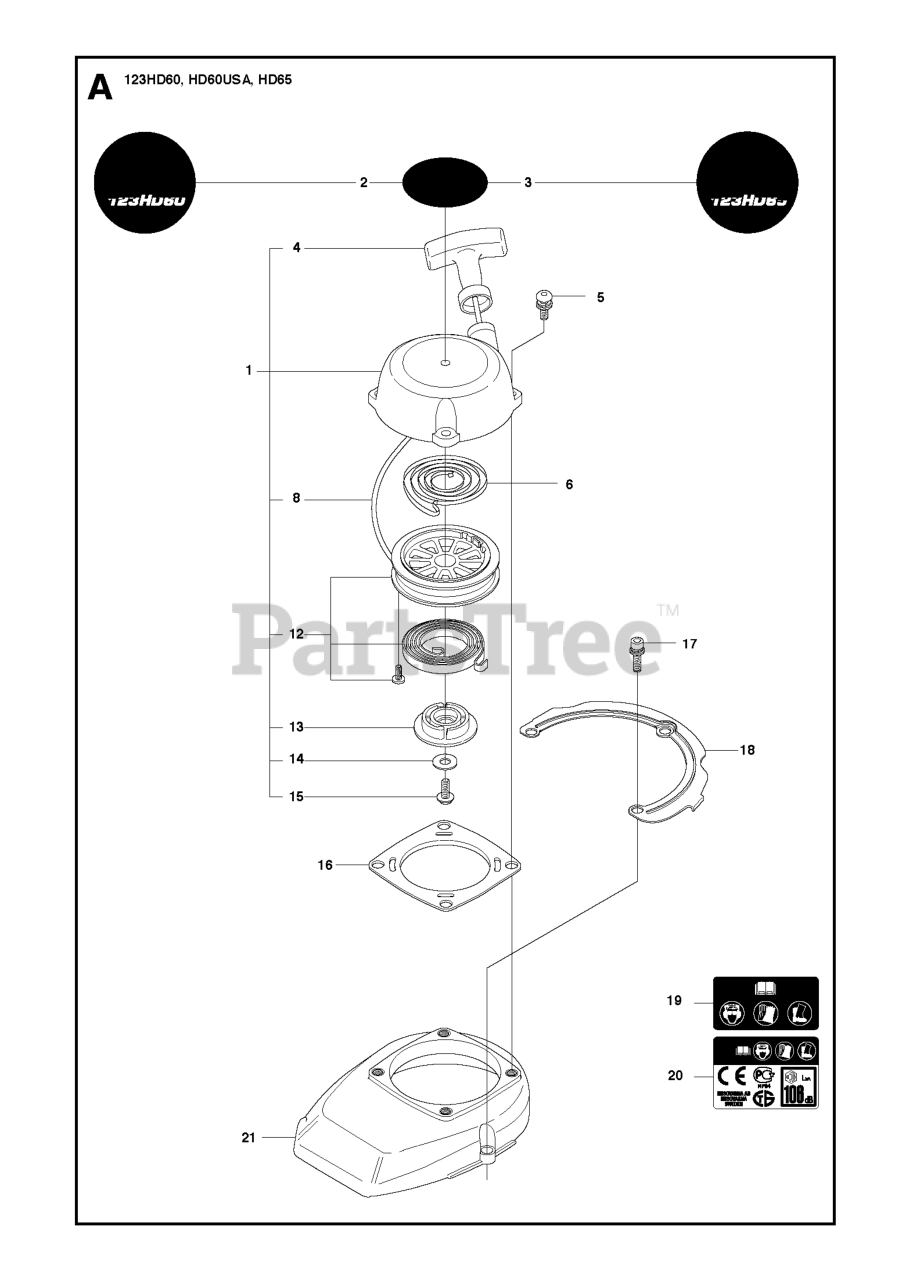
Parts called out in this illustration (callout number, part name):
1	STARTER DEVICE
2	DECAL
3	DECAL STARTER
6	RETURN SPRING
8	STARTER ROPE
12	STARTER PULLEY/SPRING ASSY
13	STARTER PULLEY
19	LABEL
20	LABEL
